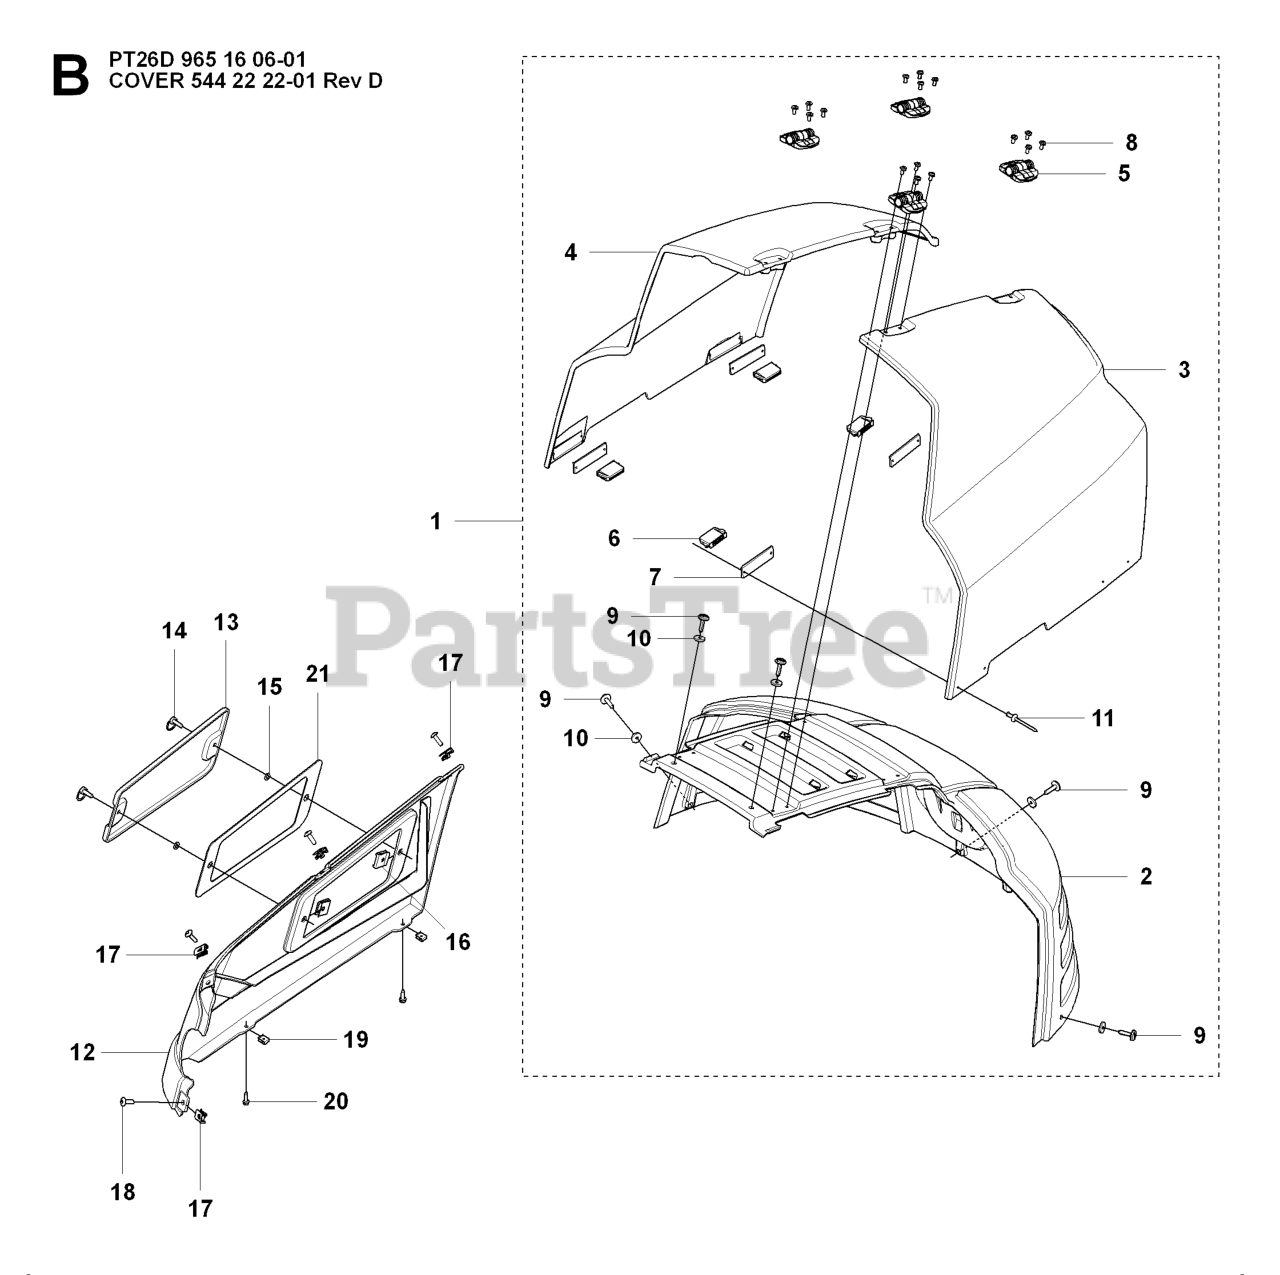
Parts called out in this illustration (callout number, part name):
2	ENGINE HOOD CENTRE PART
12	COVER CONTROL COVER SIDE ASSY
14	BOLT
21	GASKET SIDE COVER
